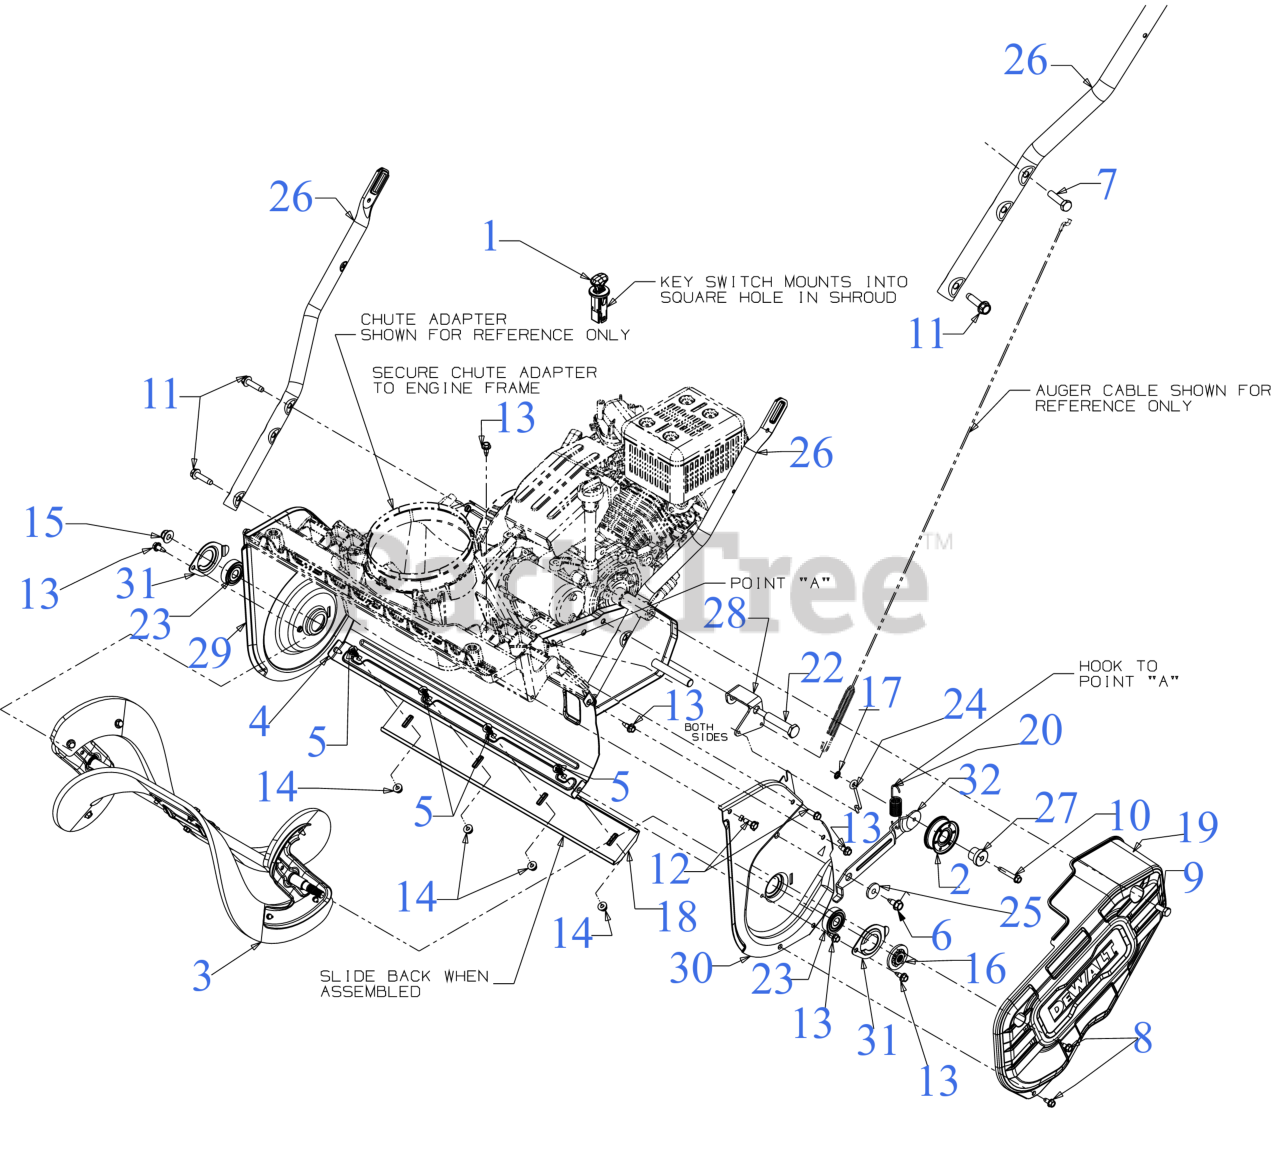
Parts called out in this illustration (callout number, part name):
1	IGNITION SWITCH
1	IGNITION KEY
2	IDLER PULLEY ASSEMBLY
3	AUGER ASSEMBLY
5	CARRIAGE BOLT 1/4-20 x .62
6	SCREW 5/16-18 x .750
7	SCREW 5/16-24 x 1.25 GR5
8	SCREW 1/4-20 X.500
9	SCREW 5/16-24 x .750 GR5
10	SCREW 1/4-20 x 1.50"
11	SCREW 5/16-18 x 1.25
12	SCREW 1/4-15 x .750
13	SCREW 1/4-20X.625
14	FLANGE LOCK NUT
16	PULLEY HUB 1/2"
17	RETAINER-BOLT .25ID x .50OD
18	SHAVE PLATE
19	BELT COVER
20	EXTENSION SPRING
22	SHOULDER BOLT
23	BALL BEARING
24	WIRE DRIVE CABLE SUPPORT
25	SHOULDER SPACER
27	SHOULDER SPACER
28	CLUTCH CABLE BRACKET
32	IDLER BRACKET
